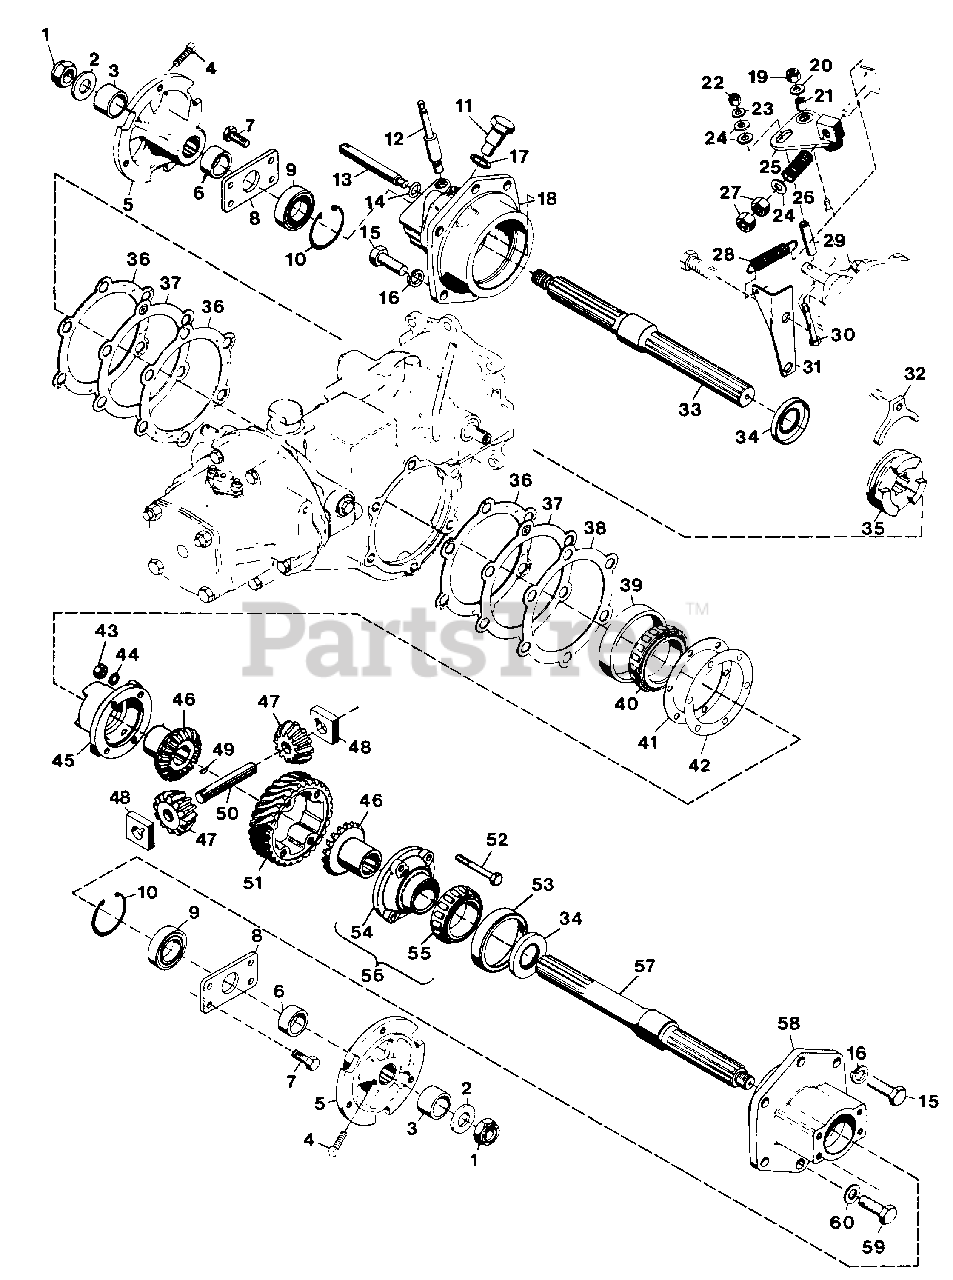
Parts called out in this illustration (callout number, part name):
1	NUT, HEX 3/4-10 LIGHT THIN
2	WASHER, FLAT .812X1.469X.134
3	SPACER
4	HUB, WHEEL
5	SCREW, SET 7/16-14X1.00 SQHCP
6	SPACER
7	PLATE, END
8	BOLT, HEX 3/8-16X.750
9	BEARING, BALL 1.000X2.000X.562
10	RING, RETAINING 2.000 BORE
11	HOUSING, AXLE
12	BOLT, HEX 1/2-13X1.00
13	WASHER, LOCK 1/2 REG.
14	AXLE, STRAIGHT
15	SEAL, OIL 1.188X2.000X.250
16	SHIM, AXLE HOUSING .005
17	GASKET, AXLE HOUSING
18	SHIM, AXLE HOUSING .020
19	CUP, ROLLER BEARING
20	CONE, ROLLER BEARING
21	NUT, HEX 5/16-24
22	WASHER, LOCK 5/16 INT. TOOTH
23	HOUSING, DIFFERENTIAL
24	ASSEMBLY, DIFFERENTIAL HOUSING
25	GEAR, DIFFERENTIAL BEVEL
26	KEY, WOODRUFF .125X.375 HARD
27	PIN, SPIDER PINION
28	GEAR, SPIDER BEVEL
29	BLOCK, DRIVE
30	GEAR, 6 LEAD WORM
31	ASSEMBLY, DIFF. STD. 6 LEAD
32	BOLT, HEX 5/16-24X2.75
33	BOLT, HEX 1/2-13X1 NYLON INSERT
34	SEAL, OIL DRAIN
